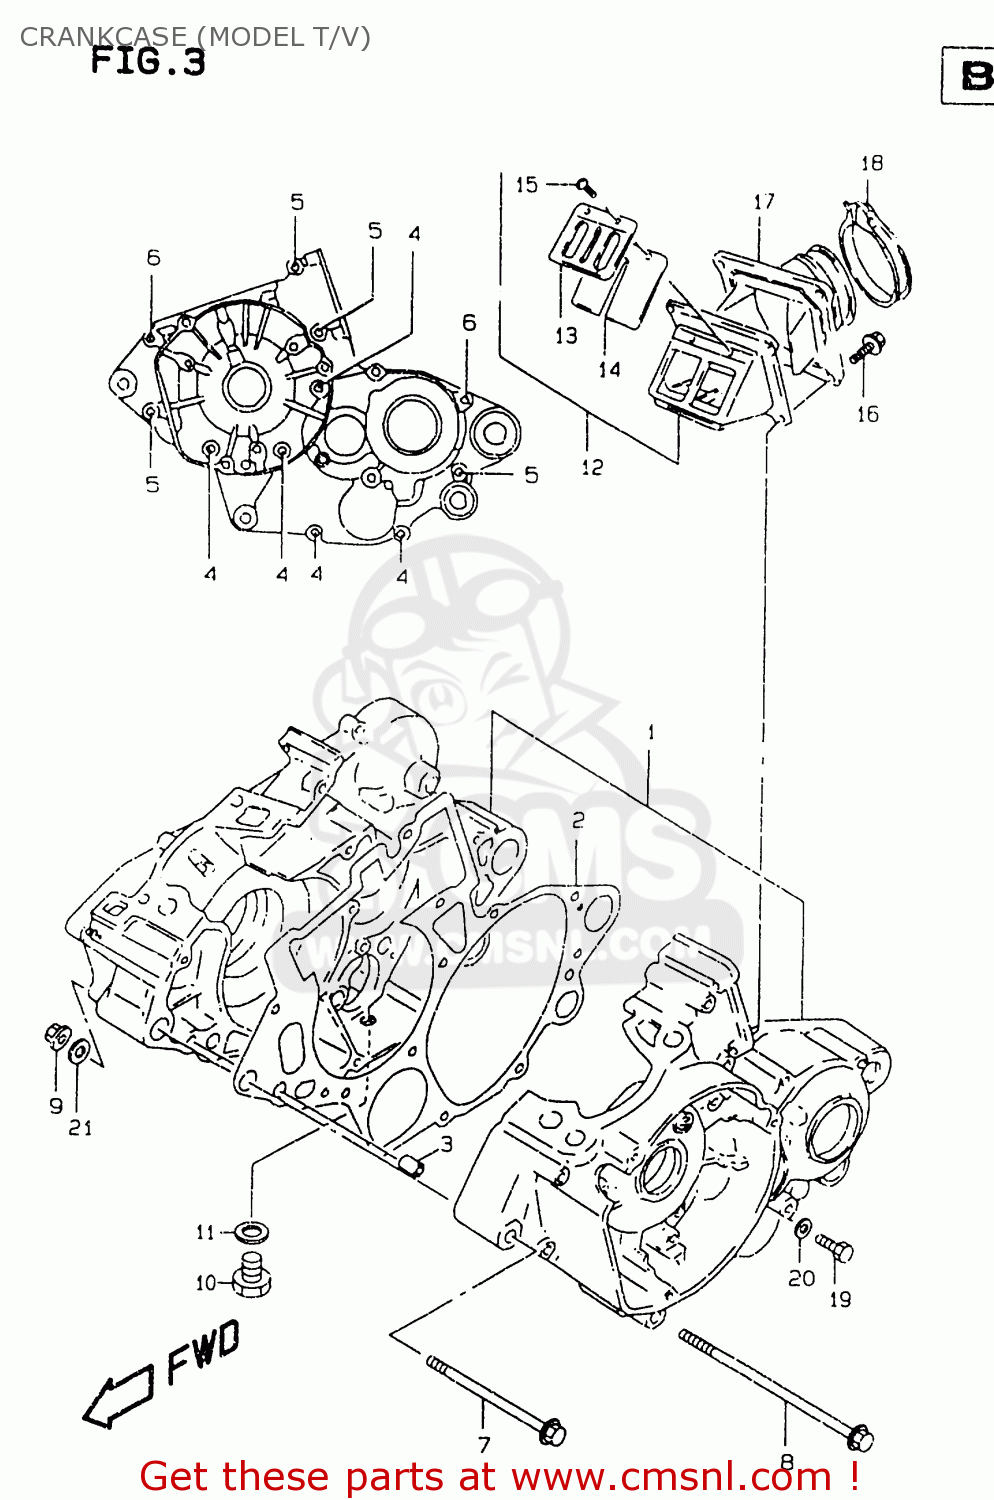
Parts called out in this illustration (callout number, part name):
1	CRANKCASE SET
2	GASKET,CRANKCASE (NAS)
3	PIN
4	BOLT
5	BOLT
6	BOLT
7	BOLT(8X88)
8	BOLT(8X125)
9	NUT
10	Bolt
11	GASKET(12.1X16.2X3.7) (NAS)
12	VALVE ASSEMBLY,REED
13	STOPPER,REED VALVE
14	VALVE,REED
15	SCREW
16	SCREW
17	PIPE COMP,INTAKE
18	CLAMP
19	SCREW(6X10)
20	GASKET(6.2X11X1).2 (NAS)
21	WASHER
